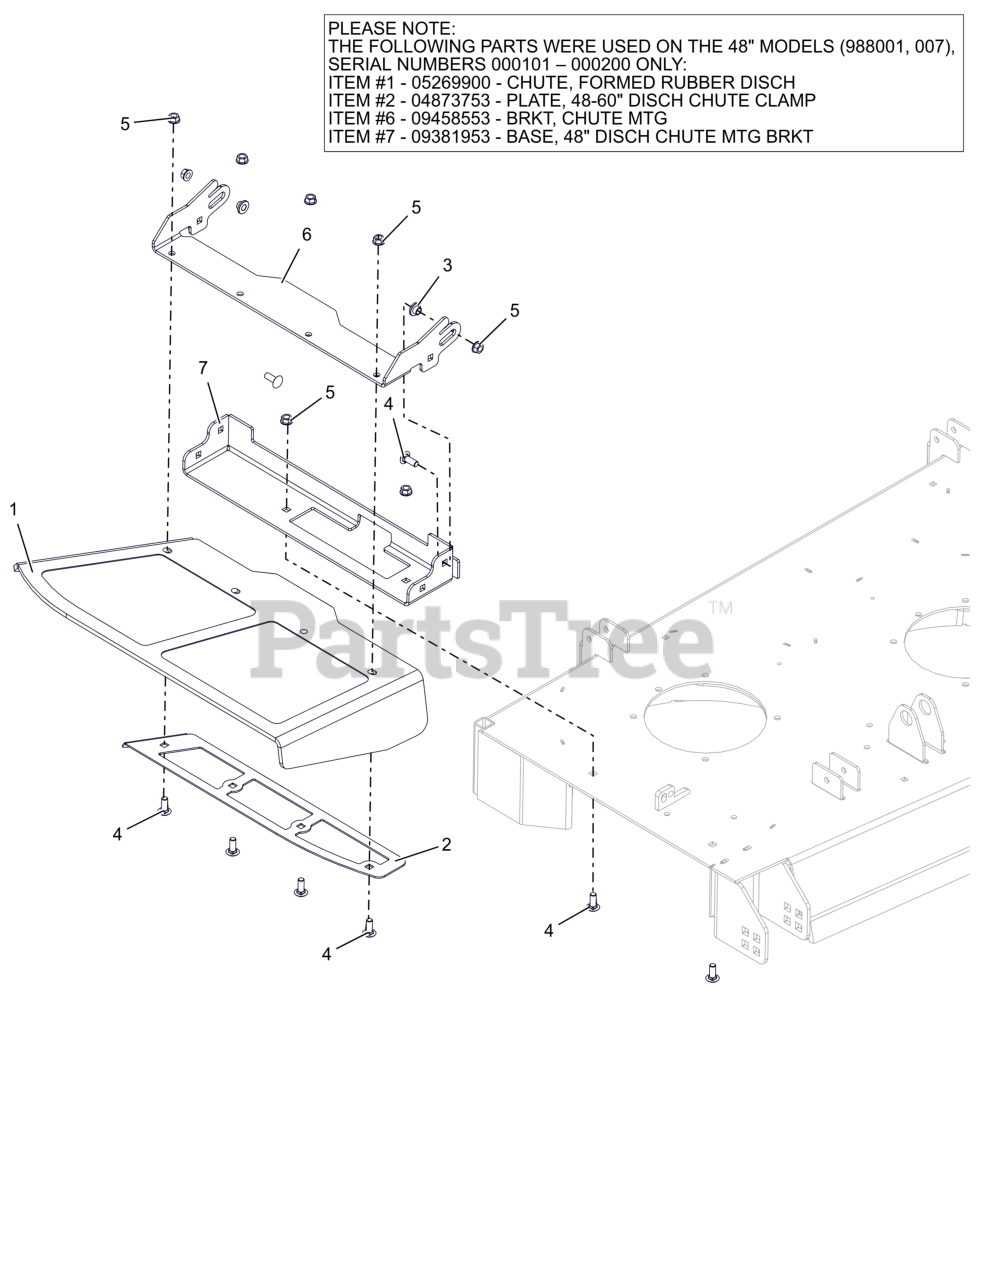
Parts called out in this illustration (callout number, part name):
1	CHUTE, FORMED RUBBER DISCHARGE-EXT
2	DISCHARGE CHUTE CLAMP PLT -RED
3	BSHG-FLG .385X.500X.875X.406
4	BLT,RHSSN .38-16X1.00 G5 ZCC
5	NUT-LK-CTR-FLG .375-16 GF ZCC
6	BRKT, CHUTE MTG (RED)
7	BASE, DISCHARGE CHUTE MTG (RED) W/ SAFETY DECALS
